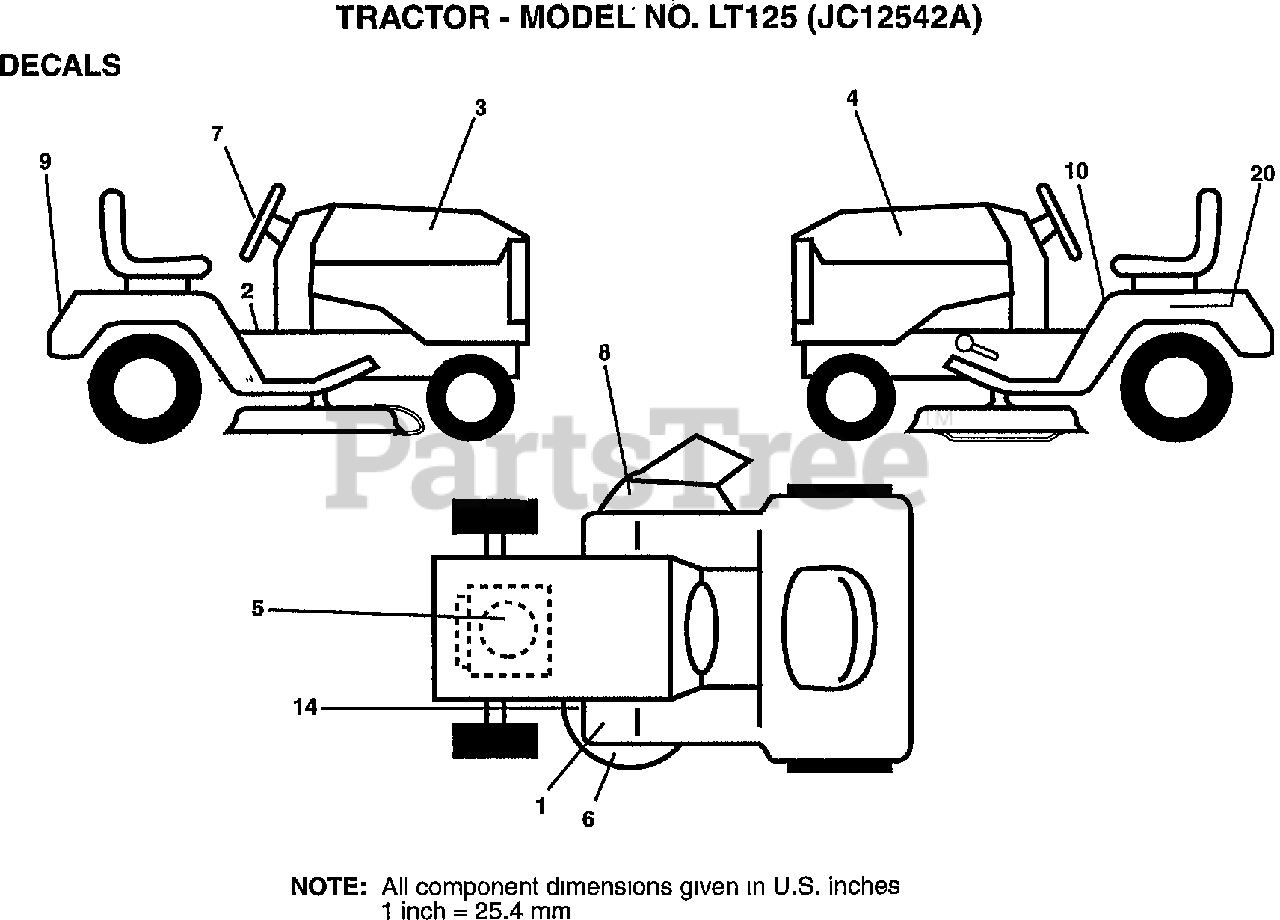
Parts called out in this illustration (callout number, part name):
2	"DECAL OPER,SADDLE"
3	DECAL HOOD RH
4	DECAL HOOD LH
6	DECAL MOWER ENVIRO WHITE
7	DECAL INS STRG
9	DECAL.FEND.LR/LT
